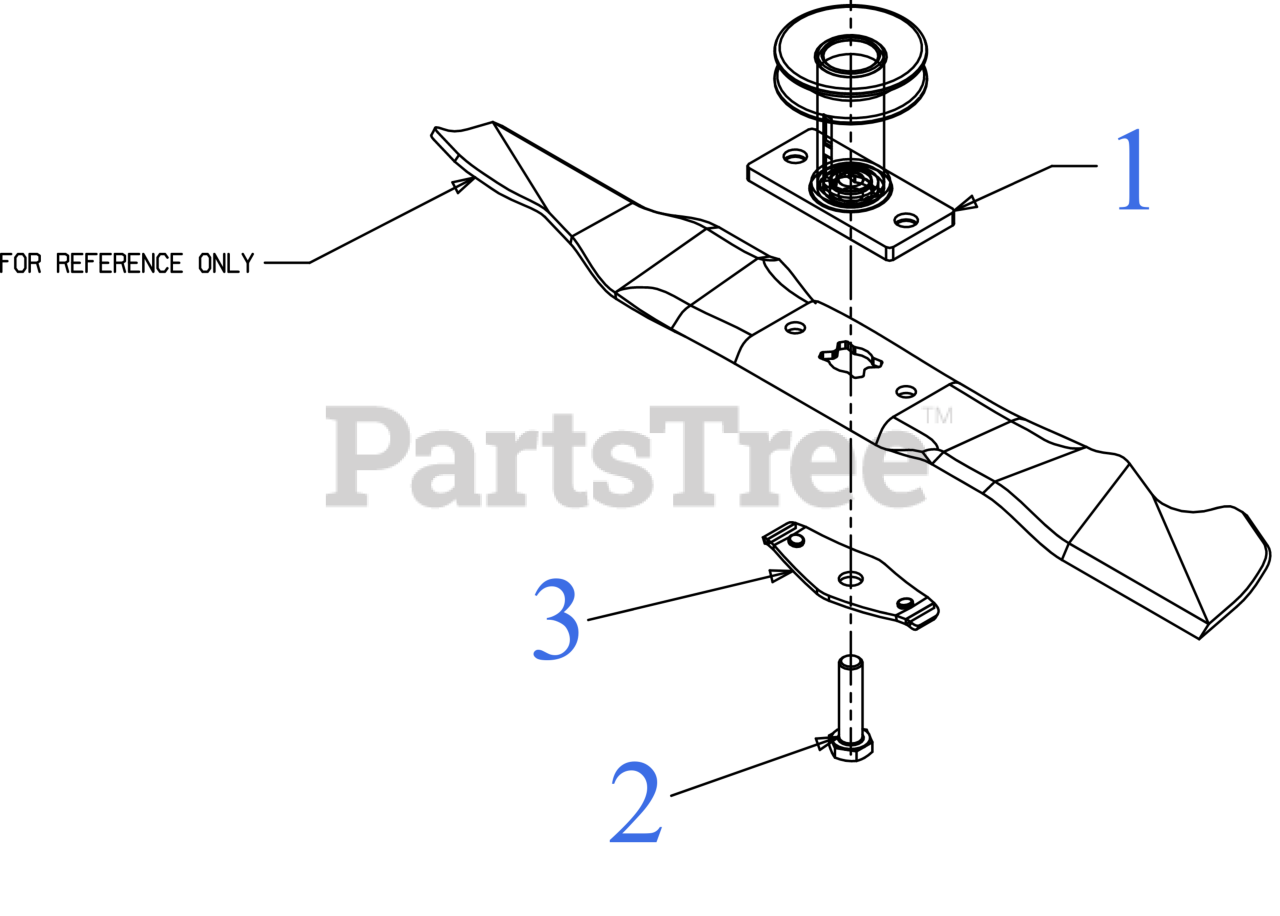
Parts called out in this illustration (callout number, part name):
1	ADAPTER ASSEMBLY(7/8 ID x .430)
2	SCREW 3/8-24 x 1.50 GR8
3	BLADE BELL SUPPORT
